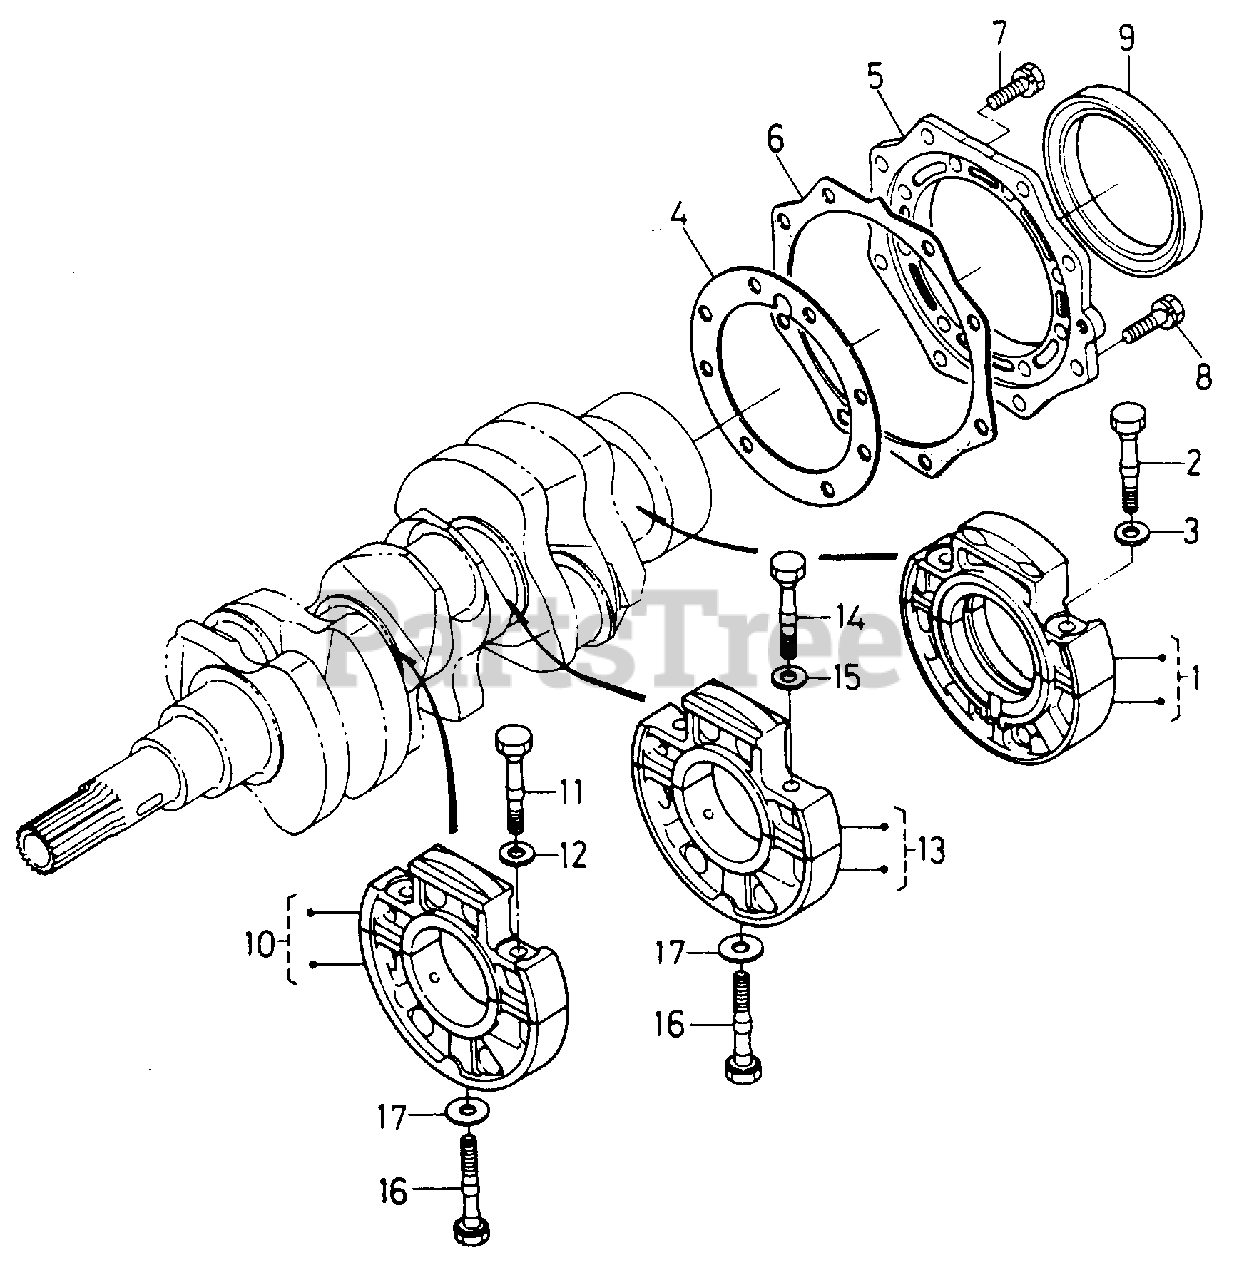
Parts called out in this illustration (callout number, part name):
1	Case, Main Bearing
2	Bolt, Bearing Case
3	Washer, Bearing Case
4	Shim, Bearing Case
5	Cover, Bearing Case
6	Gasket, Bearing Case
7	Bolt, M6 X 20 Class 8.8
10	Case, Main Bearing 1
11	Bolt, Bearing Case
12	Washer, Bearing Case
13	Case, Main Bearing
14	Bolt, Bearing Case
15	Washer, Bearing Case
16	Bolt, Bearing Case
17	Washer, Bearing Case
